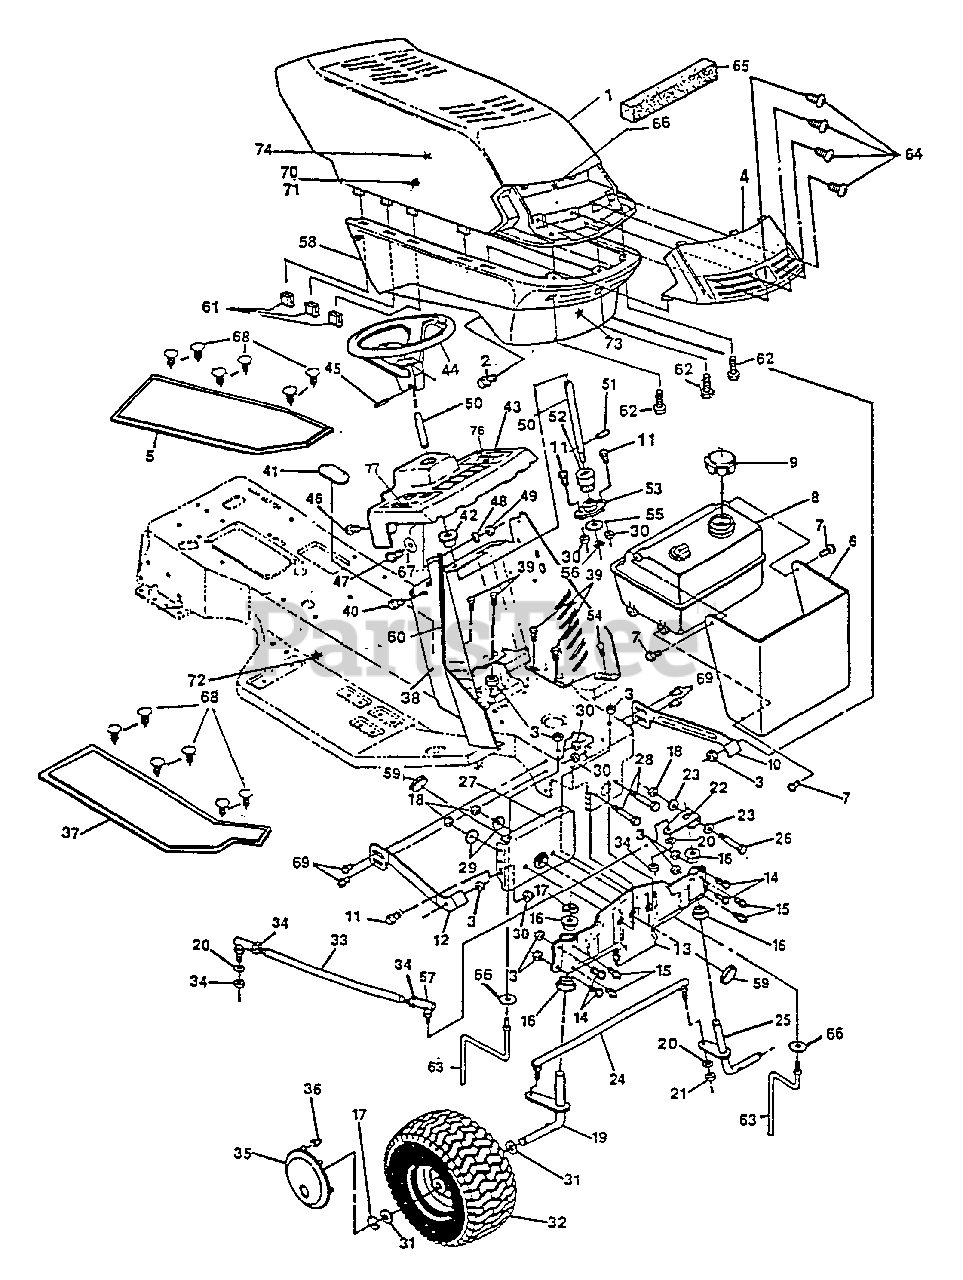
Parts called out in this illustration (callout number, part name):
2	Shoulder Bolt, 5/16-18 Thd.
3	Nut, Hx, Ctrlk, 5/16-18 Thd.
4	Lens, Headlight
5	Assembly, Foot Pad L.H.
6	Heat Shield
7	Screw, Hx Hd, Plastite 1/4 Dia. x 3/4 In.
8	Tank, Gas 1.5 Gal W/Sensor
8	Sensor, Low Fuel
9	Cap, Fuel
10	Bracket, Hood L.H.
11	Screw, Hx Hd, Wd Fl 5/16-18 x 3/4 In.
12	Bracket, Hood R.H.
13	Front Axle W/Bearings
14	Screw, Hx Hd, 5/16-18 x 5/8 In.
15	Grease Fitting
16	Bearing, Spindle
18	Nut, Hx, Ctrlk, 3/8-16 Thd.
19	Spindle, R. H.
20	Washer, Split, Lock 3/8 In.
21	Nut, Hx, 3/8-24 Thd.
22	Steering Arm, Upper
23	Washer, Flat, 25/64 In.
24	Assembly, Tie Rod
25	Spindle, L.H.
26	Screw, Hx Hd, 3/8-16 x 2-1/2 In.
27	Support Bracket, Front Axle
28	Screw, Hx Hd, 3/8-16 x 3 In.
29	Washer, Spring
30	Nut, Hx, Wd Fl Lk 5/16-18 Thd.
31	Washer, Flat, 3/4 In.
32	Wheel & Tire Assembly, Front
32	Tire, Front
32	Valve Stem
33	Drag Link Assembly
34	Nut, Hx, Jam, 3/8-24 Thd.
35	Hubcap, Front
36	Clip, Hubcap
37	Assembly, Foot Pad R.H.
38	Dash, Lower
39	Screw, Tap, 5/16-18 x 3/8 In.
40	Screw, Self-Tap, 1/4-20 x 1/2 In.
42	Bushing, Upper Steering
43	Dash, Upper
44	Steering Wheel
45	Pin, Spring, 1/4 x 2 In.
46	Screw, Tap, 1/4-20 x 1/2 In.
47	Screw, Hx Hd, 1/4-20 x 5/8 In.
48	Washer, Flat, 9/32 In.
49	Nut, Hx, Ctrlk, 1/4-20 Thd.
50	Shaft, Steering
51	Pin, Dowel
52	Pinion, Steering
53	Bearing, Flange
54	Screw, 5/16-18 Thd.
55	Washer, Flat, 1/2 In.
57	Ball, Joint, 3/8 Thd.
59	Plug, Front Axle
60	Edging, Wide, 18 (dash)
61	Clip, Hood Trim
62	Screw, #10 x 1/2 In.
63	Belt Guide
64	Screw, #4-24 x 1/2
65	Foam, Hood Baffle
66	Washer, Internal Tooth
67	Washer, Flat
68	Rachet Fastener
69	Screw, Hex, 5/16-18 x 3/4 In.
70	Decal, Stripe RH
71	Decal, Stripe LH
72	Decal, 4 Wheel Steer LH & RH
73	Decal, Gunsight Clear Back
74	Decal, Hood
75	Decal, Gunsight Center, Steering Wheel
76	Decal, Dash L.H.
77	Decal, Dash R.H.
